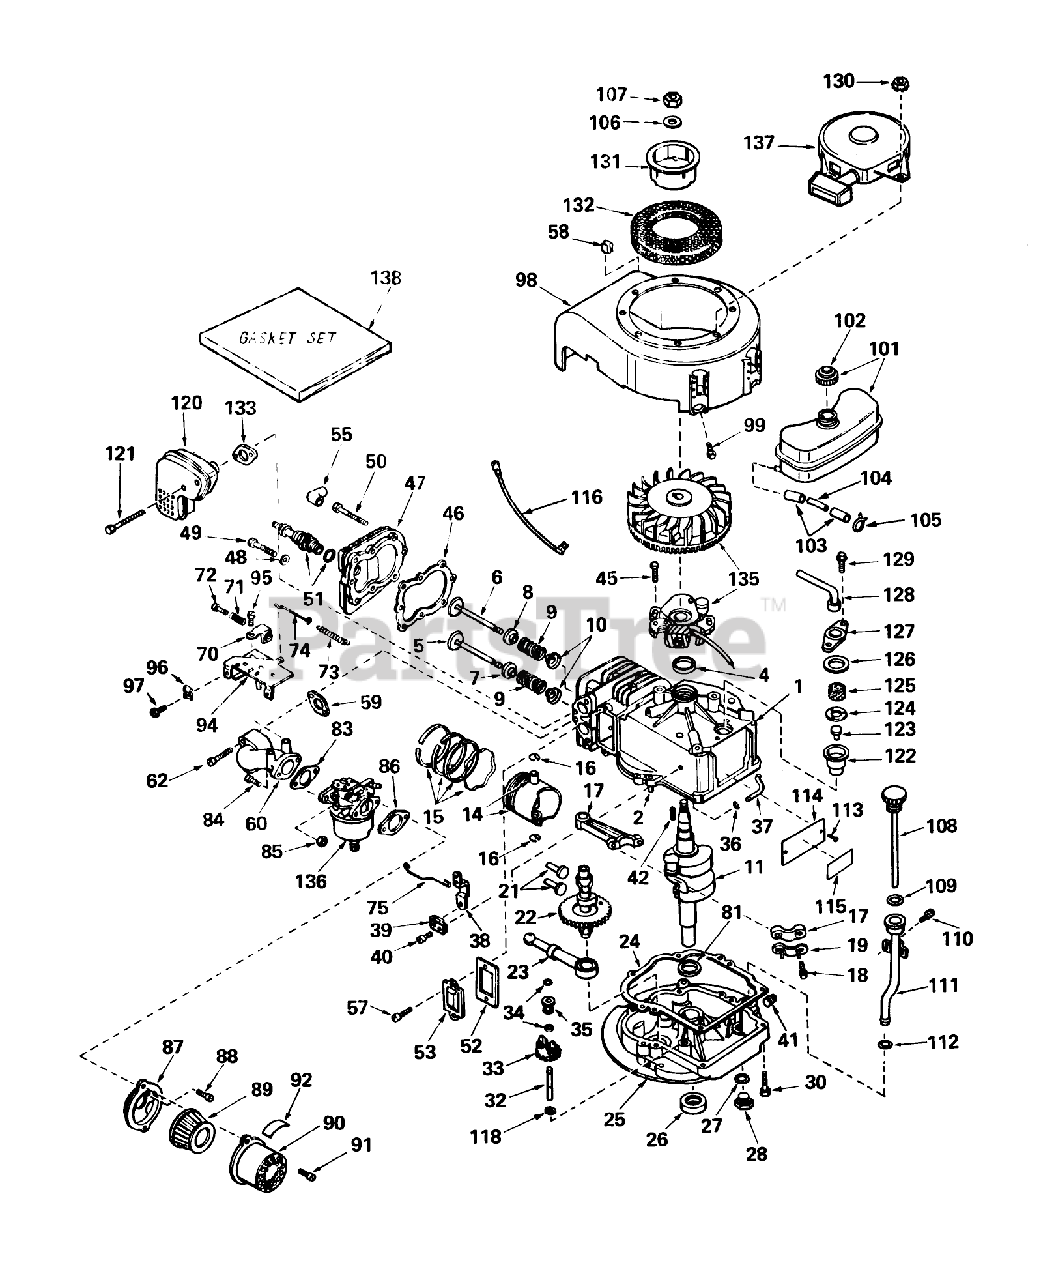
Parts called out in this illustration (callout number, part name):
1	Cylinder Assy. (Incl. Nos. 2 4)
2	Pin-Dowel
4	Seal-Oil
5	Valve, Intake (Standard) (Incl. Nos. 7, 9 10)
5	Valve, Intake (1/32" Oversize) (Incl. Nos. 7, 9 10)
6	Valve, Exhaust (Standard) (Incl. Nos. 8, 9 10)
6	Valve, Exhaust (1/32" Oversize) (Incl. Nos. 8, 9 10)
7	Cap-Upper Valve Spring
8	Cap, Upper Valve Spg (Exhaust)
9	Spring-Valve
10	Cap-Valve, Spring
11	Crankshaft
14	Piston Pin Assy. (Standard) (Incl. 2 of No. 16)
14	Piston Pin Assy. (.010 Oversize) (Incl. 2 of No. 16)
14	Piston Pin Assy. (.020 Oversize) (Incl. 2 of No. 16)
15	Ring Set-Piston Std.
15	Ring Set-Piston .010 oversize
15	Ring Set-Piston .020 oversize
16	Ring-Retaining, Piston Pin
17	Rod Assy., Connecting (Incl. Nos. 18 19)
18	Connecting Rod Bolt
19	Plate Lock
21	Lifter-Valve
22	Camshaft (Compr. Release)
23	Oil Pump ASM
24	Gasket, Mounting
25	Flange Assy., Mounting (Incl. Nos. 26, 27, 28 32)
26	Seal-Oil
27	Gasket-Oil Drain
28	Plug, Drain
30	Screw (1/4-20 x 1-1/4)
32	Shaft-Governor
33	Governor Gear ASM
34	Ring-Retaining
35	Spool-Governor
36	Washer-Flat
37	Rod, Governor (Incl. No. 36)
38	Governor Lever
39	Clamp-Lever, Governor
40	Screw
41	Plug-Pipe
42	Key Flywheel
45	Screw
46	Oil Fill Tube
47	Head Cylinder
48	Washer
49	Screw
50	Screw Hex Hd. Cap
51	Plug, Spark (J17LM or equiv.)
52	Gasket-Breather
53	Cover-Valve
55	Cover-Spark Plug
57	Screw
58	51004 GIL ROTARY TI
59	Gasket, Intake
60	Pipe, Intake
62	Screw, Fil. Slotted Hd.Sems
70	Brachet, Control
71	Spring
72	Screw, Hex Hd.
73	Spring, Governor
74	Link Governor Spring
75	Link Governor
81	Washer-Thrust
83	Gasket
85	Nut and Lock Washer (1/4-28)
86	Gasket
87	Bracket
88	Screw (10-32 x 1/2)
89	Element
90	Body
91	Screw
92	Decal
94	Control Assy., Speed
95	Screw (10-24 x 9/16)
96	Conduit
97	Screw (10-32 x 3/8)
98	Housing, Blower
101	Tank Assy., Fuel (Incl. No. 102)
102	Cap, Fuel
103	Line-Fuel (8.62)
104	Line, Fuel
105	Clamp-Line, Fuel
106	Washer-Spring
107	Hex Nut
108	Dipstick, Assy., Oil (Incl. No.109)
109	O-Ring
110	Screw (10-32 x 1/2)
111	Tube Assy., Oil Fill
112	O-Ring
113	Stud
114	IDENTIFICATION PLATE
115	480B GIL SNWTHWR O/
116	SPOOL RETAINER (10-PK)
118	Washer-Flat
120	Muffler
121	Screw-Fil. Hd.
122	Body Breather Tube
123	Valve Check
124	2000A37 WIZARD ROTA
125	Element-Breather
126	Gasket-Breather
127	Cover Breather
128	Tube, Breather
129	Screw, Hex Hd. w/Conical
130	Nut and Lock Washer (1/4-28)
131	Cup, Starter
132	Screen-Starter
133	Gasket-Exhaust
135	Magneto
136	Carburetor
137	Starter, Rewind
138	Gasket Set
